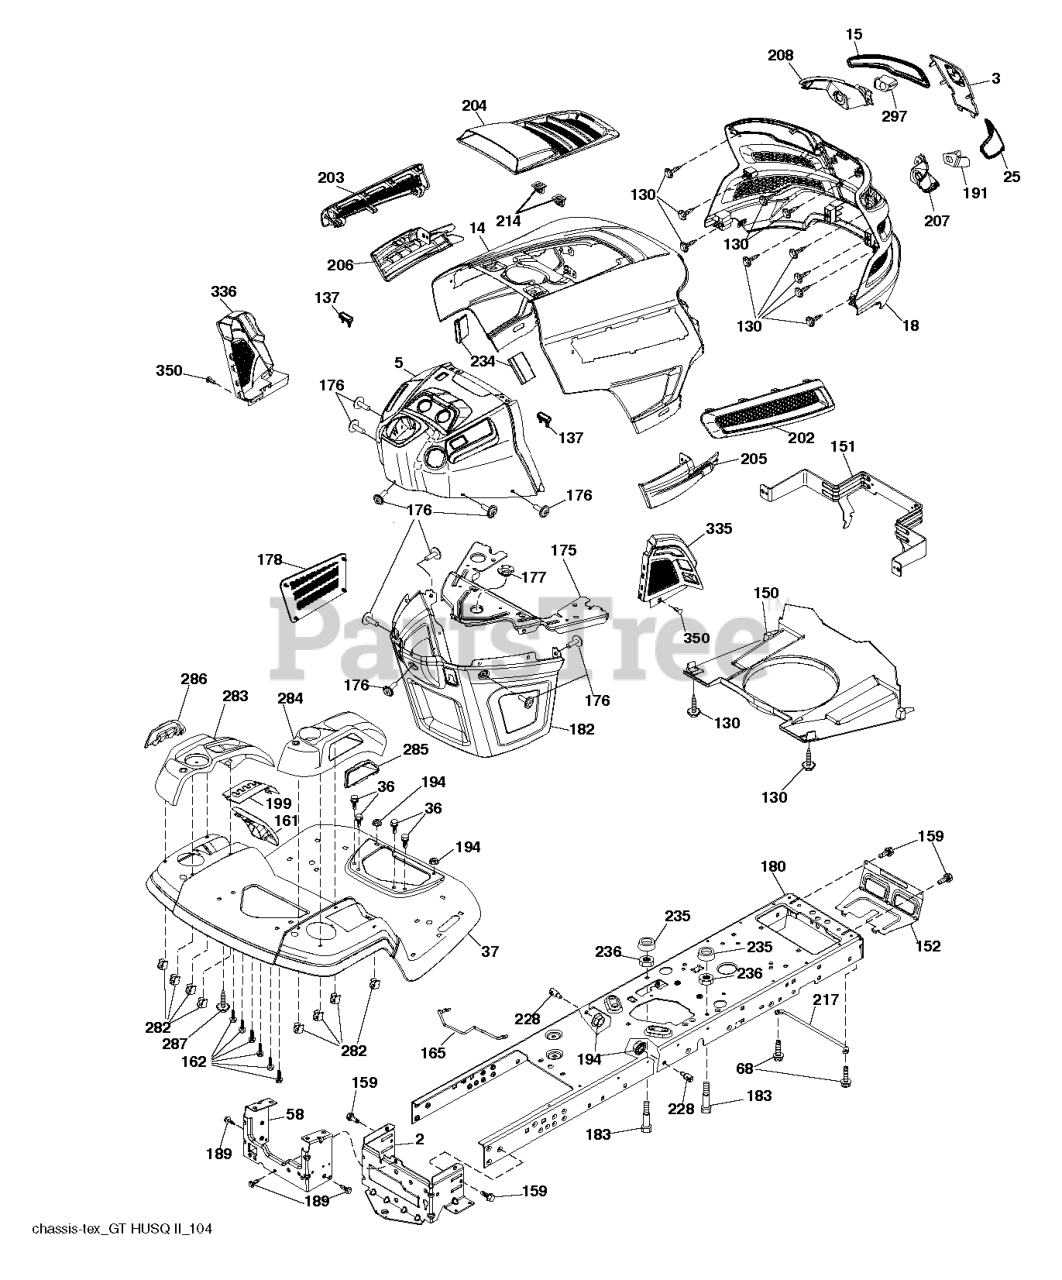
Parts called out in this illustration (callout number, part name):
2	DRAWBAR.LOWER.2PC.18/22
3	APPLIQUE.SUBASM.GT.HUSQ.II
5	DASH.UPP.GT2.DUAL.RD.PTO.MCHOK
14	HOOD.ASM.HUSQVARNA.GT.TEX.ORAN
15	LENS.HEADLIGHT.LH.GTII.2011
18	GRILLE.SUBSTRATE.2011.
25	LENS.HEADLIGHT.RH.GTII.2011
36	SCREW 5/16"
37	FENDER.TLT.FS.W/CPH/FW/RSF.668
58	DRAWBAR UPPER 2PC SMALL FENDER
68	Screw 5/16-18 x 1/2 Hex, Self Tapping 5/16-18 x 1/2
130	SCREW.#10 X 0.750.BOS
137	BUMPER DASH
150	AIR.DUCT.GTV2(2.54"RING HEIGHT
151	BRACKET.PIVOT.HOOD.GT.HUSQ.II
152	SHIELD.BROWNING/DEBRIS
159	SCREW, 3/8-16X3/4
161	WINDOW FUEL
162	SCREW.HI-LO.CONSOLE
165	SUPPORT.TANK.REAR.B/TE
175	PLATE.CROSSMEMBER.HUSQ
176	SCREW.#10-24X5/8.RN.QU
177	BUSHING, STEERING
178	CARGO.ASM.NET.TXGT.W/C
180	CHASSIS.STAMPING.LT/GT
182	DASH.LOWER.COMMON.12V.ADAPTOR
183	BOLT.5/16-18X1-1/4 FULL THD
189	SCREW
191	INSERT.REFLECTIVE.RH.HUSQ.GTII
194	NUT LOCK HEX FLANGE 5/16-18
199	PLATE.DECK.LIFT.HUSQ.LT
202	VENT.SIDE.RH.GT.HUSQ.II.
203	VENT.SIDE.LH.GT.HUSQ.II.498
204	VENT.TOP.HUSQ.GT2
205	SIDE.TRIM.RH.GT.HUSQ.II
206	SIDE.TRIM.LH.GT.HUSQ.II.GRAY
207	BEZEL LIGHT.RH.GT.II.MYLAR
208	BEZEL LIGHT.LH.GT.II.MYLAR
214	CLIP.RETAINER.TINNER.
217	ROD.PIVOT.HOOD
228	STUD.FASTNER.W/ANTI-ROTATE
234	BUMPER.HOOD.TEX.HUSQVARNA
235	SPACER FENDER
236	NUT.CENTERLOCK.5/16-
282	CLIP.RETAINER.CONSOLE.LT.HUSQ
283	CONSOLE.DECK.LFT.R.SDFL.HUSQLT
284	CONSOLE.CNTRL.
285	CONSOLE INSERT RH
286	CONSOLE.INSRT.LH.HUSQ.LT.BLACK
287	SCREW 1/4X20
297	INSERT.REFLECTIVE.LH.HUSQ.GTII
335	COVER.LOWER.DASH.RH.BLACK
336	COVER.LH.CLOSE.OUT
350	CLIP.X-MAS.TREE
